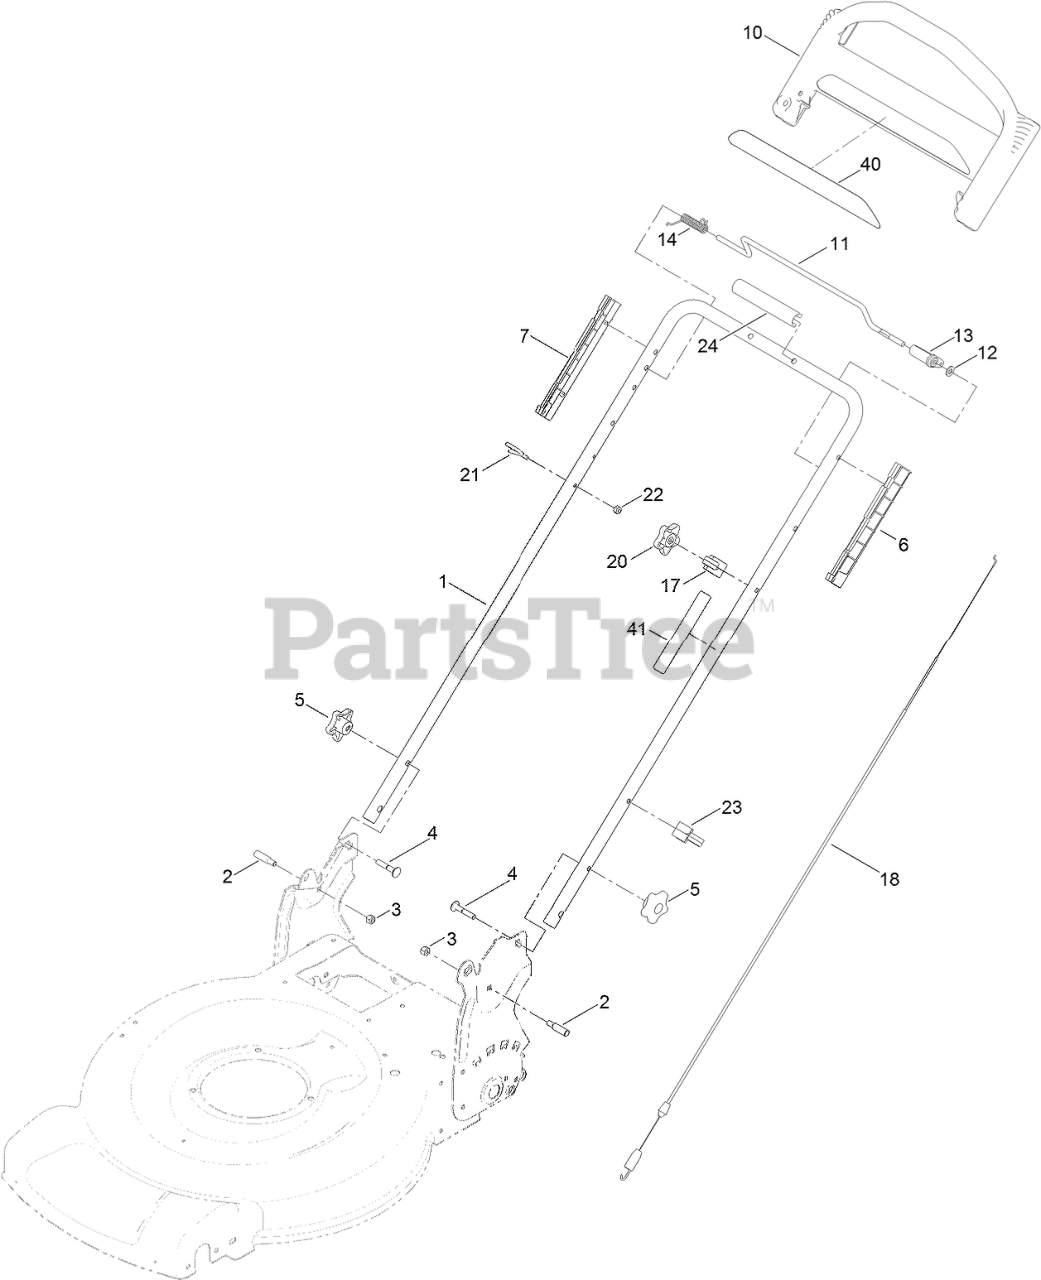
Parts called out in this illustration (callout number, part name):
2	BOLT-SHOULDER
3	NUT-LOCK, NI
4	SCREW-CARR
5	KNOB-HANDLE
6	GUIDE-LH
7	GUIDE-RH
10	HANDLE-CONTROL
12	WASHER-PLAIN
13	LEVER-TRACTION
17	ANCHOR-CABLE
18	CABLE-TRACTION
20	KNOB-HANDLE, LOCKING
21	GUIDE-ROPE
22	NUT-LOCK, NI
23	GUIDE-CABLE
24	HANDLE-COVER
40	DECAL-HANDLE
41	DECAL-TRACTION, ADJUST
